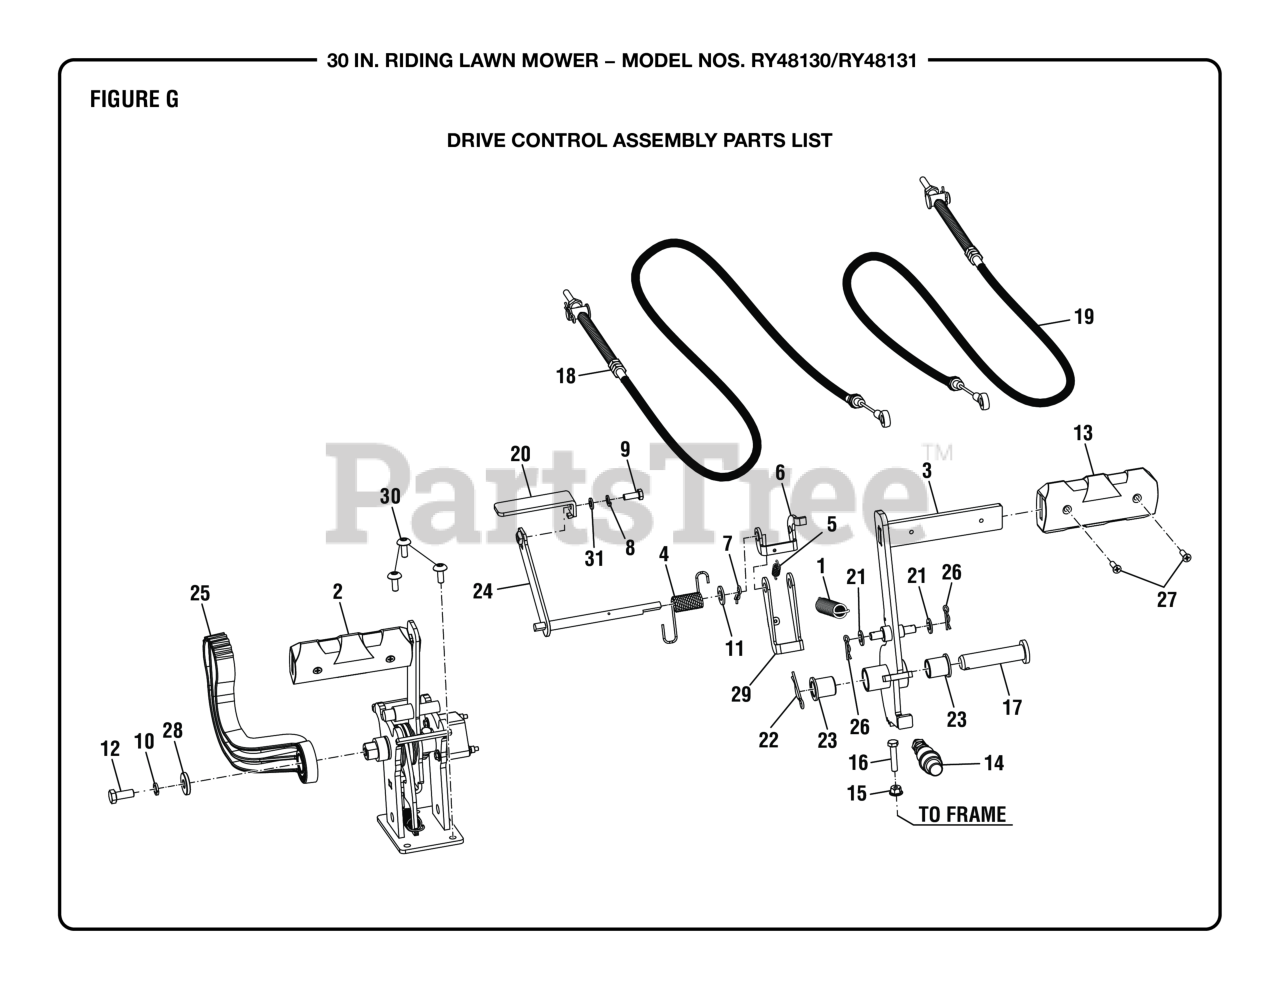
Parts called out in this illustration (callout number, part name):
1	Pedal Spring
2	Drive Assembly
3	Brake Pedal Lever
4	Return Spring
5	Spring (Parking Brake)
7	Cotter Pin (10 mm)
8	Spring Washer (M6) (For Deck Motor Controllers T & U)
9	Bolt (M6 x 16 mm, Hex Hd.)
10	Lock Washer (OD9.8 x ID8.5 x 5t)
11	Washer (OD20 x ID10.5 x 2t)
12	Hexagon Bolt (M8 x 20 mm)
13	Brake Pedal
14	Brake Switch Assembly
15	Flange Nut (M6)
16	Bolt (M6 x 30 mm, Hex Hd.)
17	Clevis Pin
18	Brake Cable (Right)
19	Brake Cable (Left)
20	Parking Brake Pedal
21	Washer (OD16 x ID8.4 x 1.6t)
22	Lock Pin (16 mm)
24	Parking Brake Lever
25	Reverse Pedal
26	Cotter Pin (8 mm)
27	Screw (M5 x 16 mm, Flat Hd.)
28	Washer (OD12.5 x ID8.4 x 4t)
29	Parking Brake Latch
30	Screw (M6 x 10 mm, Soc. Button Hd.)
31	Washer (OD12 x ID6.4 x 1.6t) (For Deck Motor Controllers T & U)
